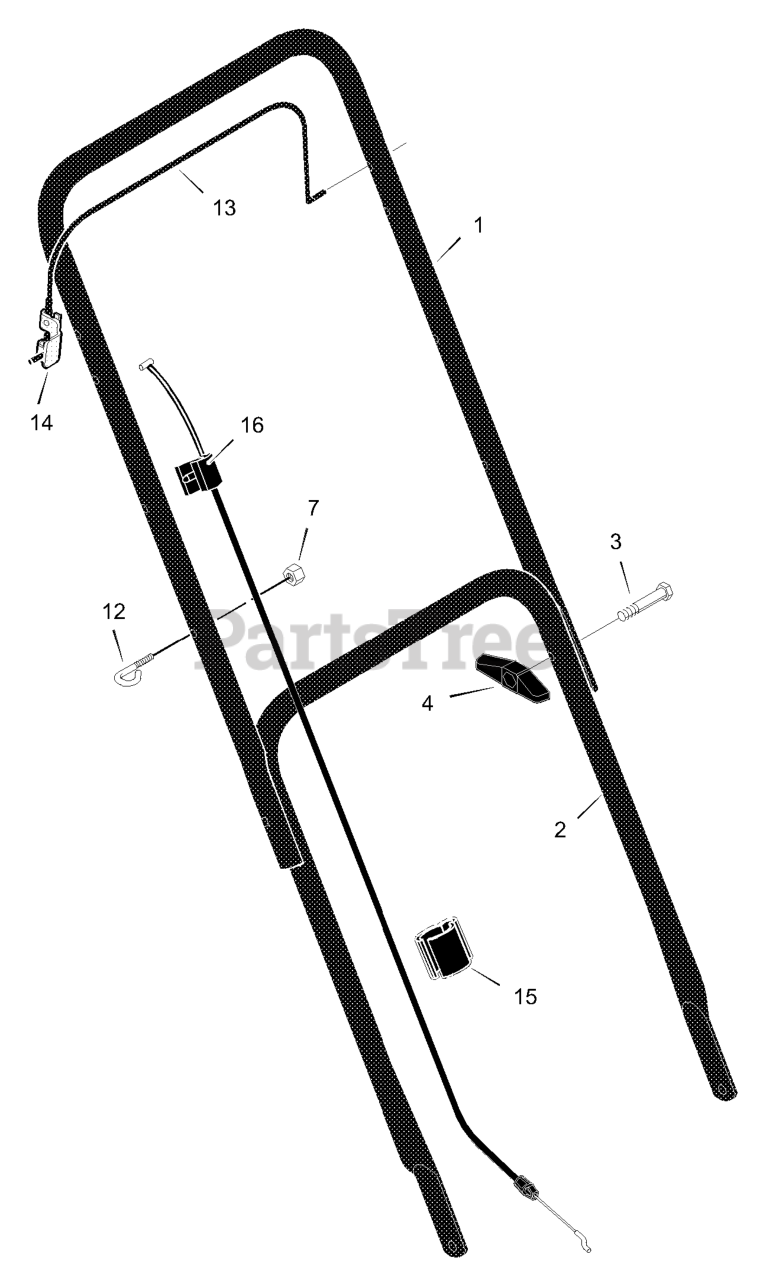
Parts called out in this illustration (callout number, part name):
1	Handle, Upper (Black)
2	Handle, Lower (Black)
4	Knob, Plastic
7	Locknut
12	Guide, Rope
13	Engine Stop Lever
14	Bracket, Stop Lever
15	Fastener, Single Cable
16	Engine Stop Cable
